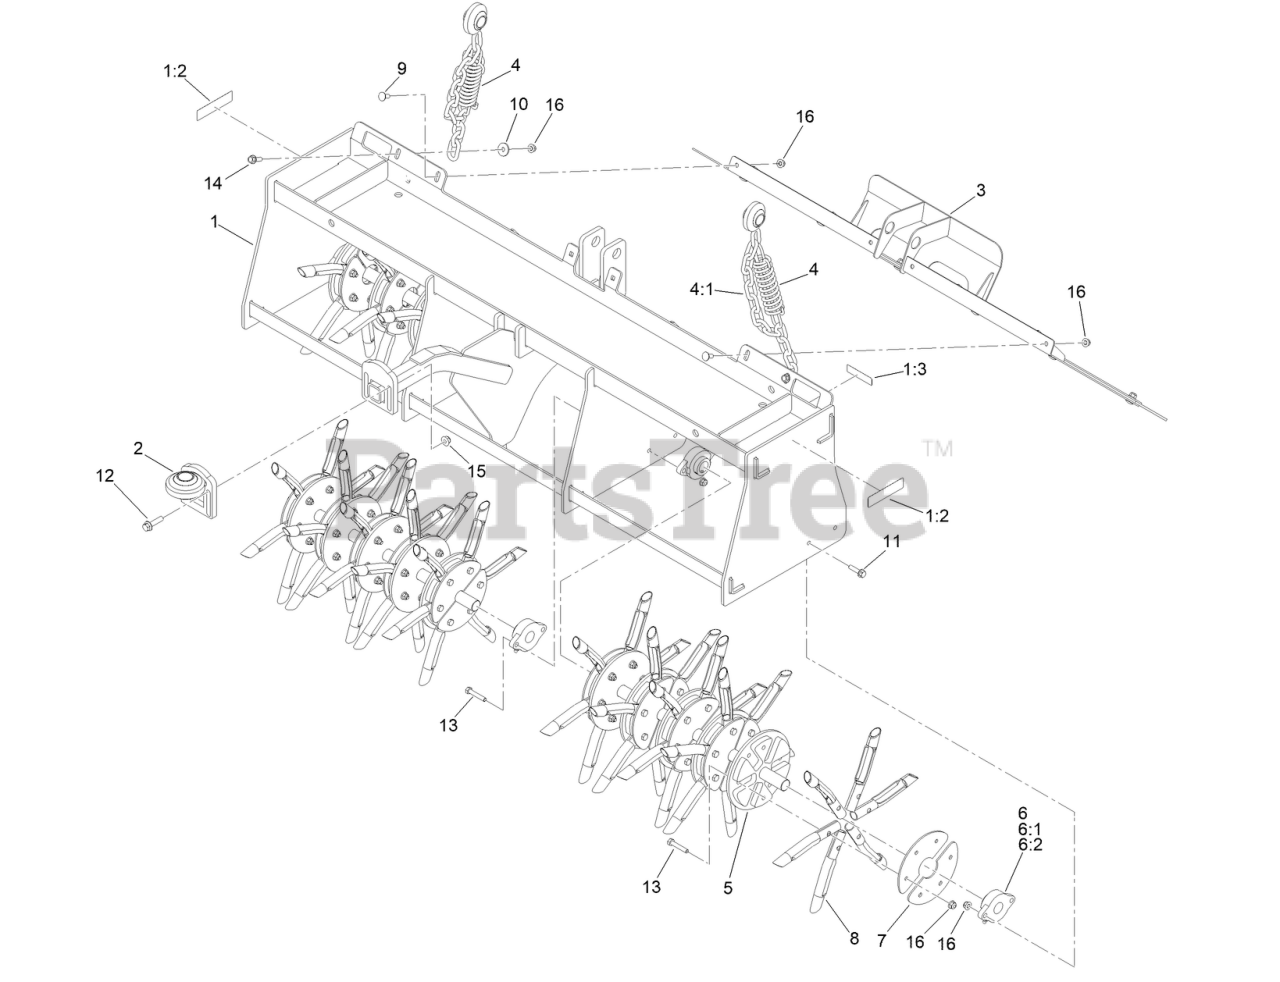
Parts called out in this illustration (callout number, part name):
1	AERATOR HEAD 50 W/DECALS
1:2	DECAL-WARNING, TINES
1:3	DECAL-WARNING
2	MOUNT-SWIVEL BRG,AER HEAD
3	Dirt Flap ASM
4	SWIVEL-CHAIN ASM
4:1	Z-PLUG DRAWBAR SPRING
5	TINE-REEL
6	BEARING-FLANGE, 2 BOLT
6:1	Zerk 1/4-28 Str Thrd Forming
6:2	SCREW-SET, HSH
7	PLATE-RETAINER, TINE
8	TINE-CORING (3/4 INCH)
9	SCREW-CARR
10	WASHER-FLAT
11	SCREW-HHF
12	SCREW-HHF
13	SCREW-HH
14	SCREW-HH
15	NUT-HF, NI
16	NUT-HF, NI
